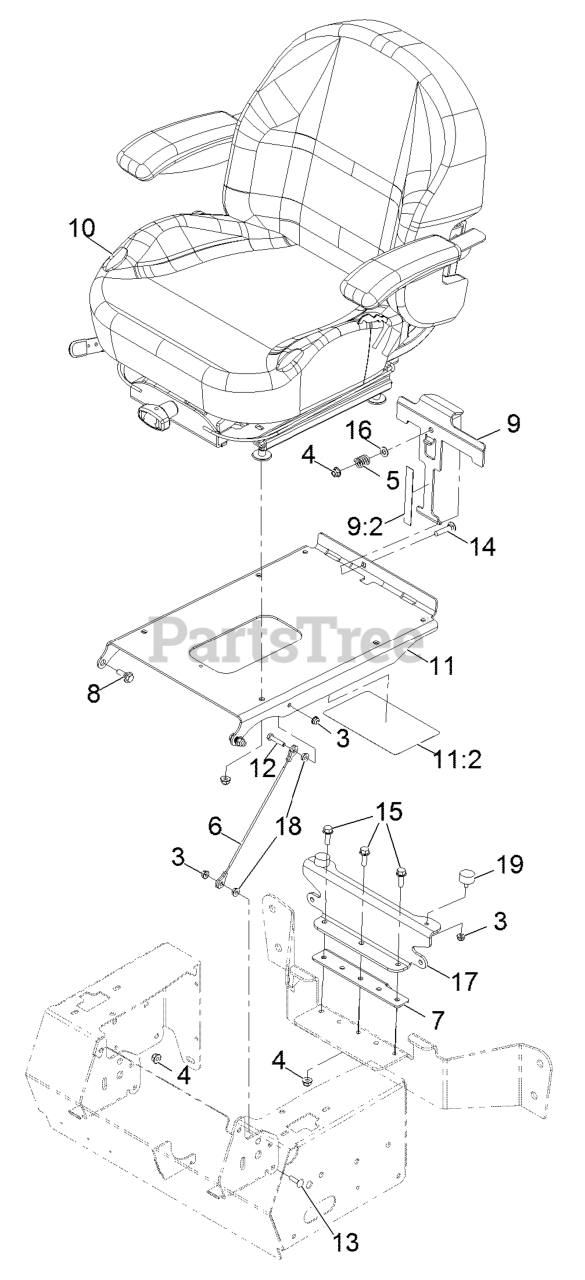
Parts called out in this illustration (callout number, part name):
4	NUT-HF, NI
5	SPRING-COMPRESSION
6	CABLE-STOP, SEAT
7	CATCH,SEAT LATCH
8	SCREW-SHOULDER
9	ASM-SEAT LATCH
9:2	STRIP-POLY WEAR
10	KIT-SEAT SUSPENSION
11	PLATE, SEAT W/DECALS
11:2	DECAL-SERVICE AID
12	SCREW-HH
13	SCREW-CARR
14	BOLT-CARR
15	SCREW-HHF
16	WASHER-PLAIN
17	PLATE-SEAT SUPPORT
19	BUMPER-RUBBER
